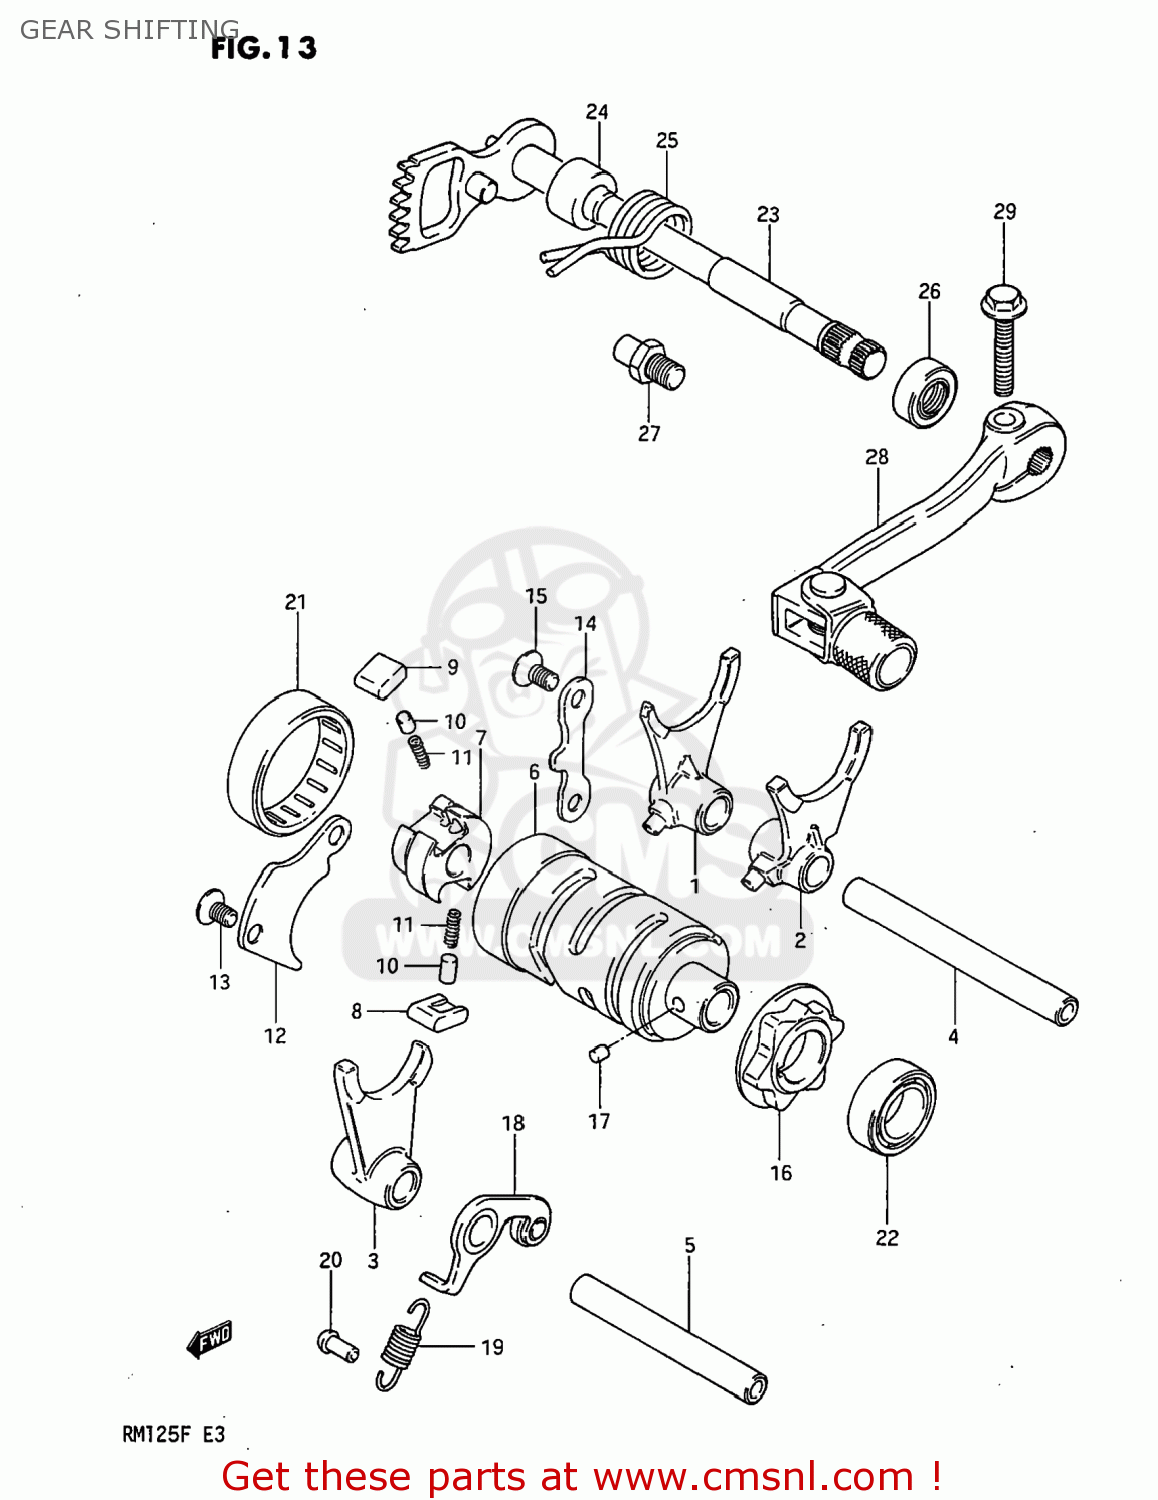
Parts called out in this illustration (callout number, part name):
1	FORK,GEAR SHIFT NO.1
2	FORK,GEAR SHIFT NO.2
3	FORK,GEAR SHIFT NO.2
4	SHAFT,GEAR SHIFT FORK
5	SHAFT,GEAR SHIFT FORK
6	CAM,GEAR SHIFT
7	GEAR,GEARSHIFT CAM DRIVE
8	PAWL,GEAR SHIFT NO.1
9	PAWL,GEAR SHIFT NO.2
10	PIN(5X8)
11	SPRING
12	LIFTER,GEAR SHIFT PAWL
13	SCREW
14	GUIDE,GEAR SHIFT CAM
15	SCREW
16	PLATE,GEAR SHIFT CAM STOPPER
17	PIN
18	STOPPER,GEAR SHIFTING
19	SPRING
20	RIVET
21	BEARING
22	BEARING
23	SHAFT,GEAR SHIFT
24	SPACER(12X20X15.3)
25	SPRING
26	OIL SEAL
27	STOPPER,GEAR SHIFT CAM
28	LEVER ASSY,GEAR SHIFT
29	BOLT
